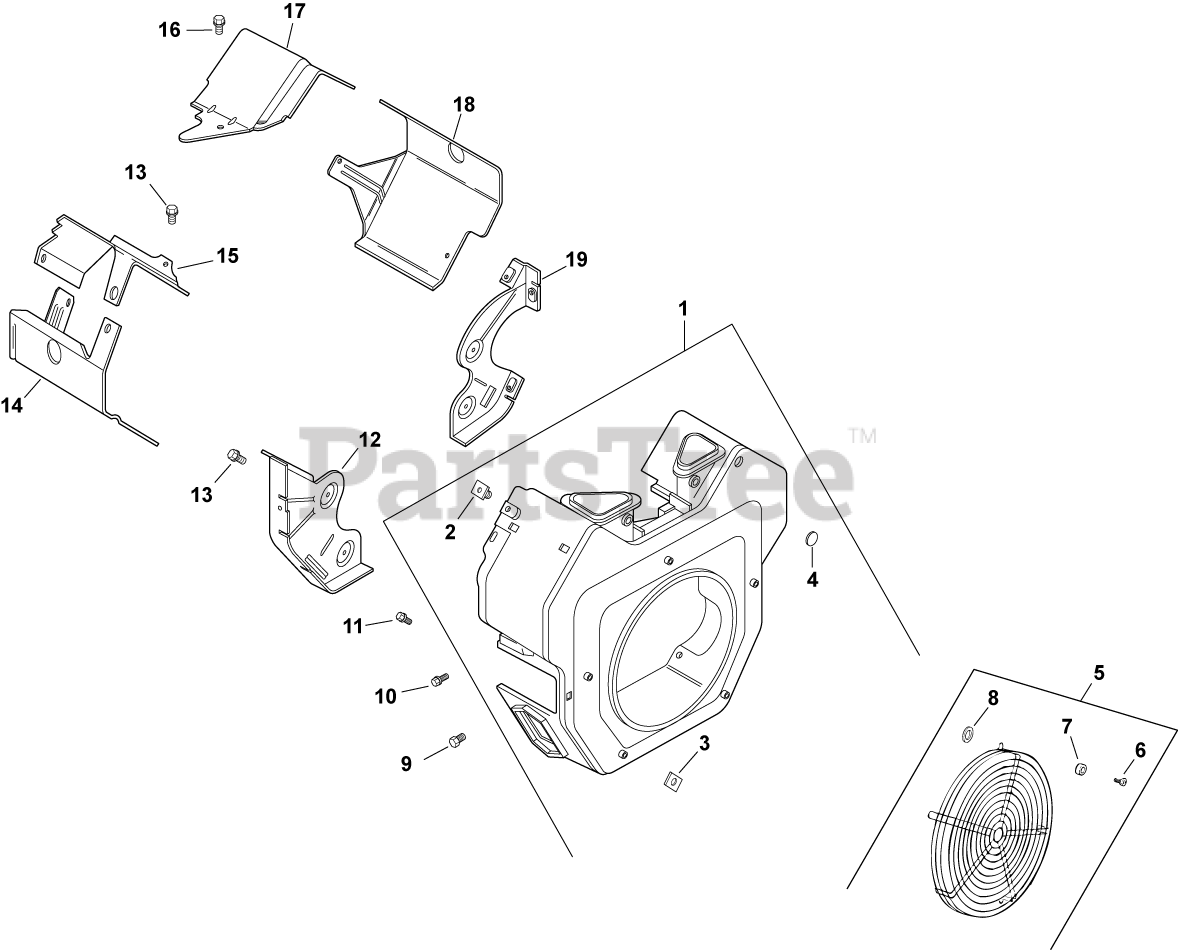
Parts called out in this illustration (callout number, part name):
1	KIT, BLOWER HOUSING ASSY-(#24027492S)
2	NUT, PLASTIC (KM)-USE 25 100 37-S
3	NUT, PLASTIC
4	PLUG, BUTTON 9/16
5	KIT, GUARD
6	SCREW, PAN HEAD-USE 25 086 160-S
7	SPACER USE 25 112 30-S
8	WASHER, FLAT 7/32"
9	SCREW, HVY FLG M5X.8X16
10	SCREW,FLG THD FRM M5X0.8X16-(#25086398S)
11	SCREW, FLG THD FRM M5X.8X20-(#25086399S)
12	PLATE, BACKING #2 SIDE
13	SCREW,FLG THD FRM M6X1.0X16-(#25086397S)
14	BAFFLE,VALLEY #2SIDE(KM)-USE 24 063 88-S
15	BAFFLE, VALLEY #2 SIDE-USE 24 063 94-S
16	SCREW, FLG THD FRM M5X.8X10
17	BAFFLE, VALLEY (CH)-USE 24 063 93-S
18	BAFFLE, RIGHT BARREL-USE 24 063 85-S
19	PLATE, BACKING - DISCONTINUED
